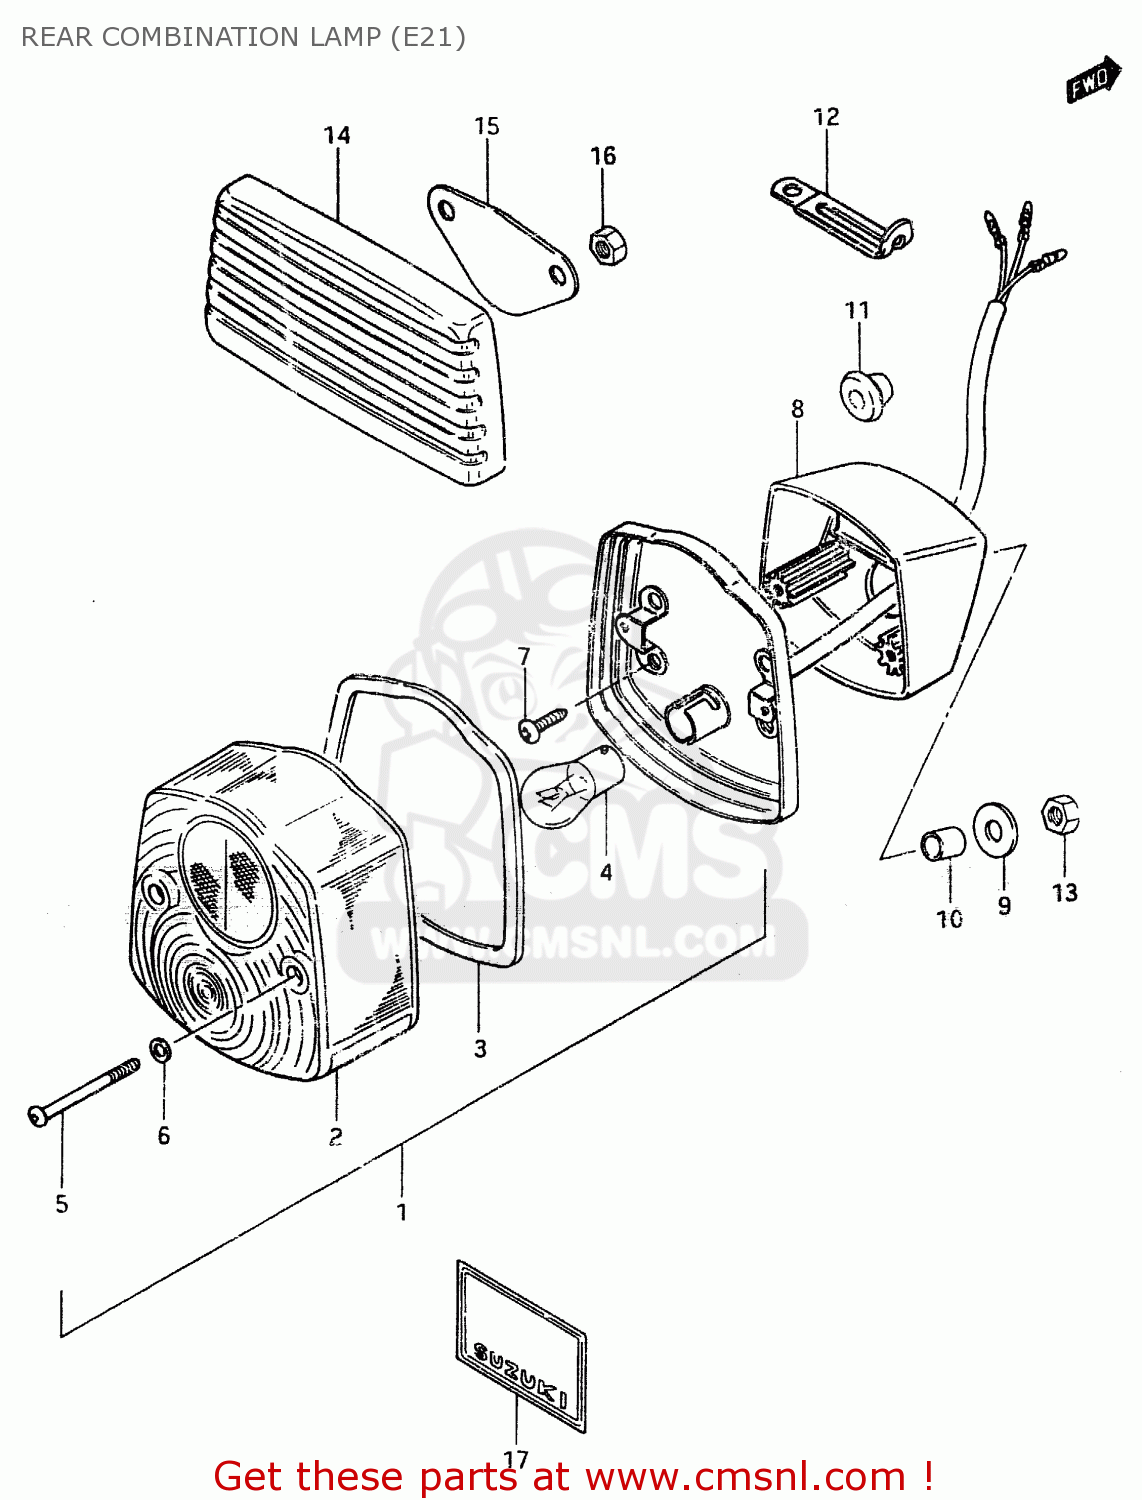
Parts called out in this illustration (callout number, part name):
1	LAMP UNIT, TAIL
2	LENS,RR COMBI
3	GASKET (NAS)
4	BULB (6V,21/5W)
5	SCREW
6	GASKET (NAS)
7	SCREW
8	BRACKET ASSY
9	WASHER
10	SPACER(6.1X9X7.5)
11	GROMMET
12	CLAMP L:35
13	NUT
14	COVER
15	PLATE
16	NUT
17	EMBLEM, REAR
